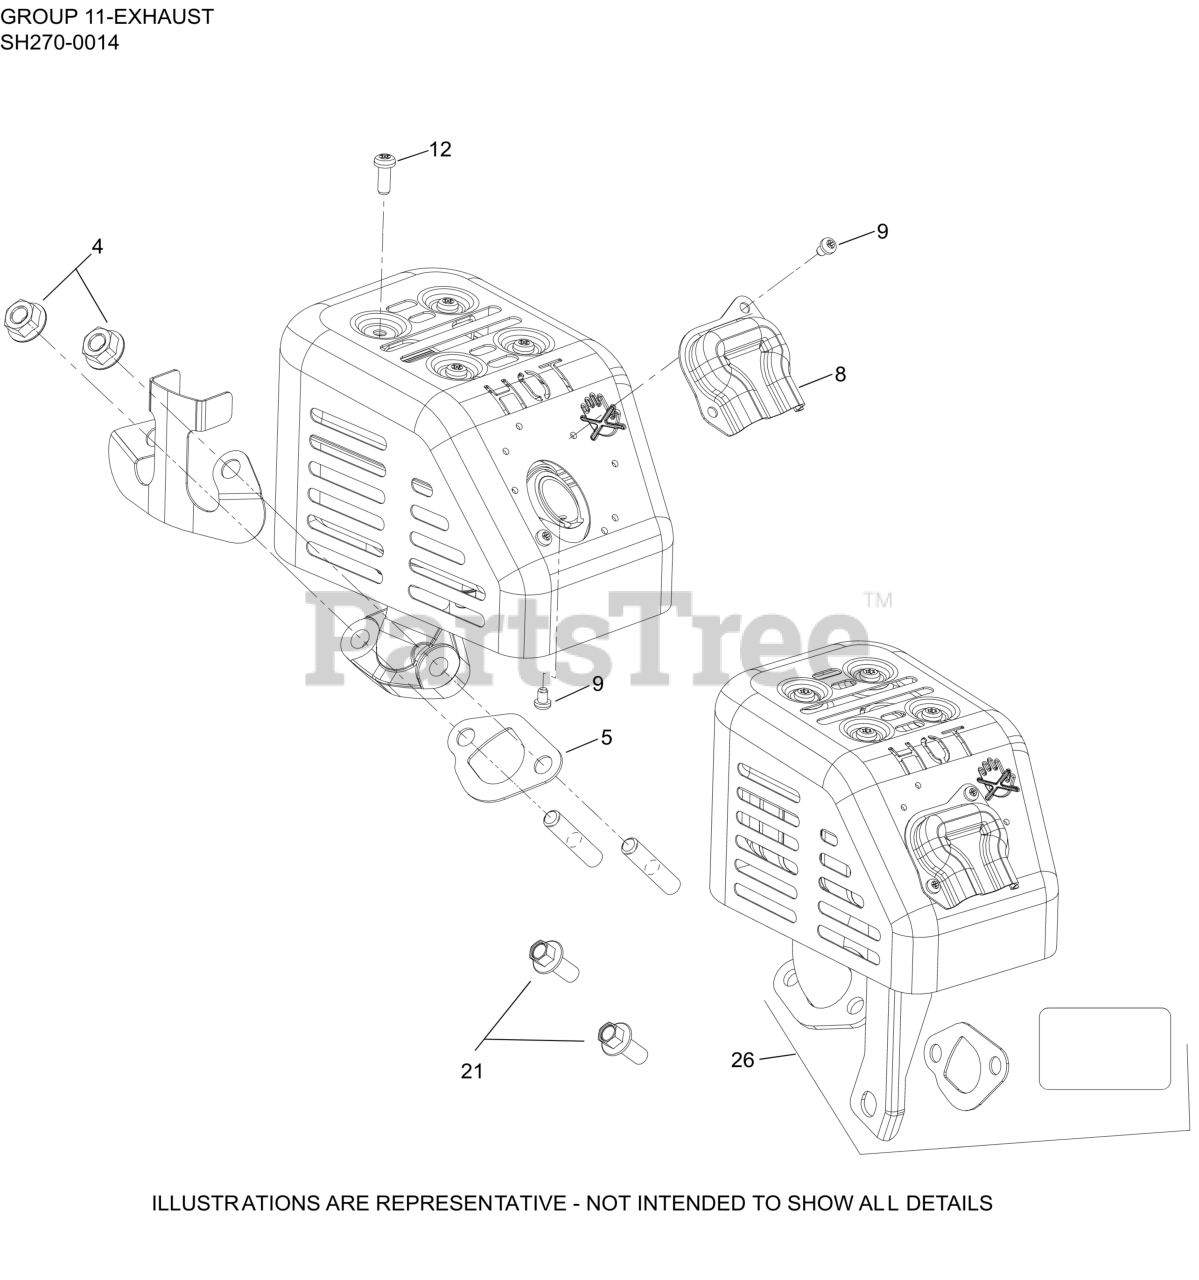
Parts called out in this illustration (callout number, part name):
4	NUT, HEX FLANGE (M6) - USE 14 100 16-S
5	GASKET, EXHAUST
8	DEFLECTOR, EXHAUST - USE 18 730 01-S
9	SCREW, SPARK ARRESTOR
12	SCREW, M5 X 10
21	SCREW, M8 X 20
26	KIT, MUFFLER
